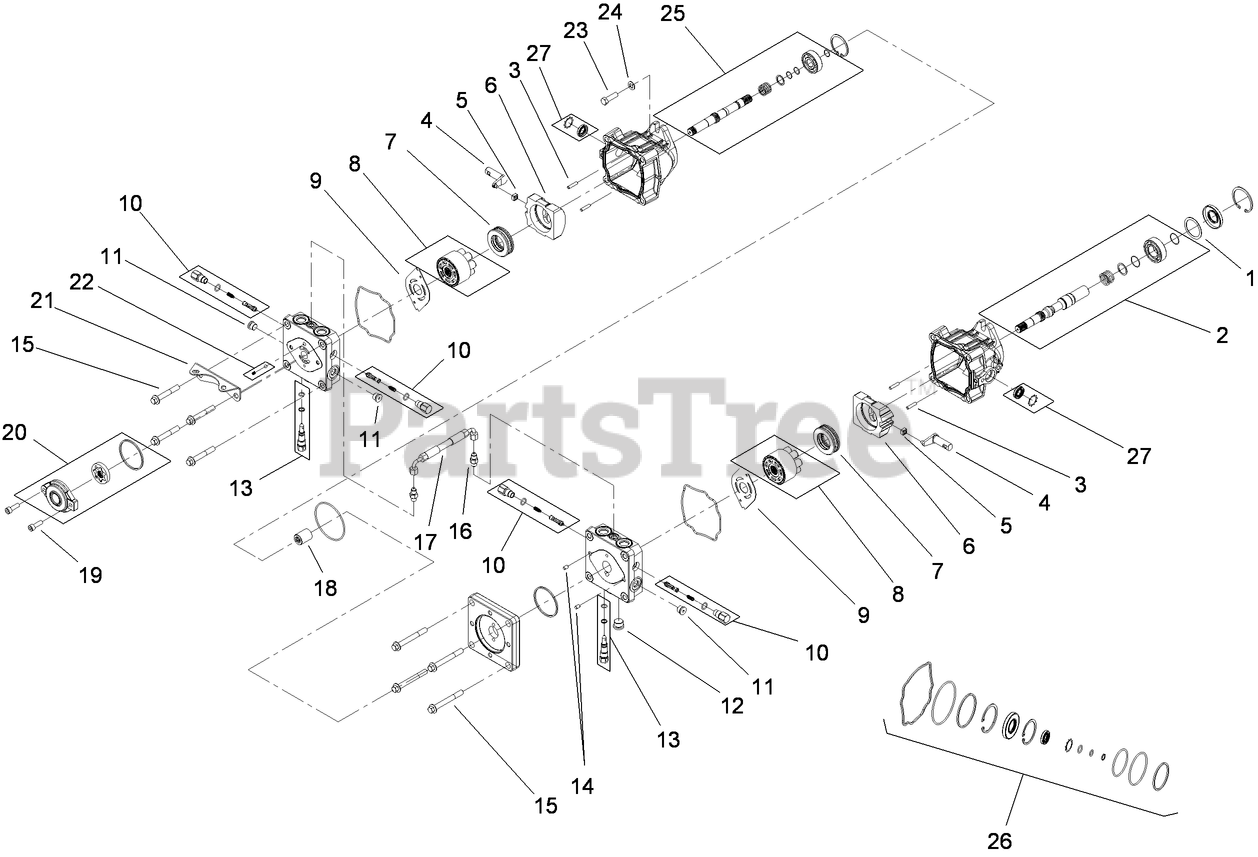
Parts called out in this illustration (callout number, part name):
1	SPACER
2	INPUT PUMP SHAFT KIT
3	PIN-HEADLESS, STRAIGHT
4	ARM-TRUNNION
5	GUIDE-SLOT
6	SWASHPLATE
7	BEARING-THRUST
8	CYLINDER BLOCK KIT
9	PLATE-VALVE
10	SHOCK VALVE KIT
11	PLUG-THREAD, STRAIGHT
12	PLUG-STEEL
13	BYPASS VALVE KIT
16	FITTING-STRAIGHT
17	HOSE ASM
18	COUPLING
20	CHARGE PUMP KIT
21	BRACKET-SUPPORT, PUMP
22	CHARGE RELIEF KIT
23	BOLT-HSH
24	WASHER
25	SECOND PUMP SHAFT KIT
26	OVERHAUL SEAL KIT
27	TRUNNION SEAL KIT
